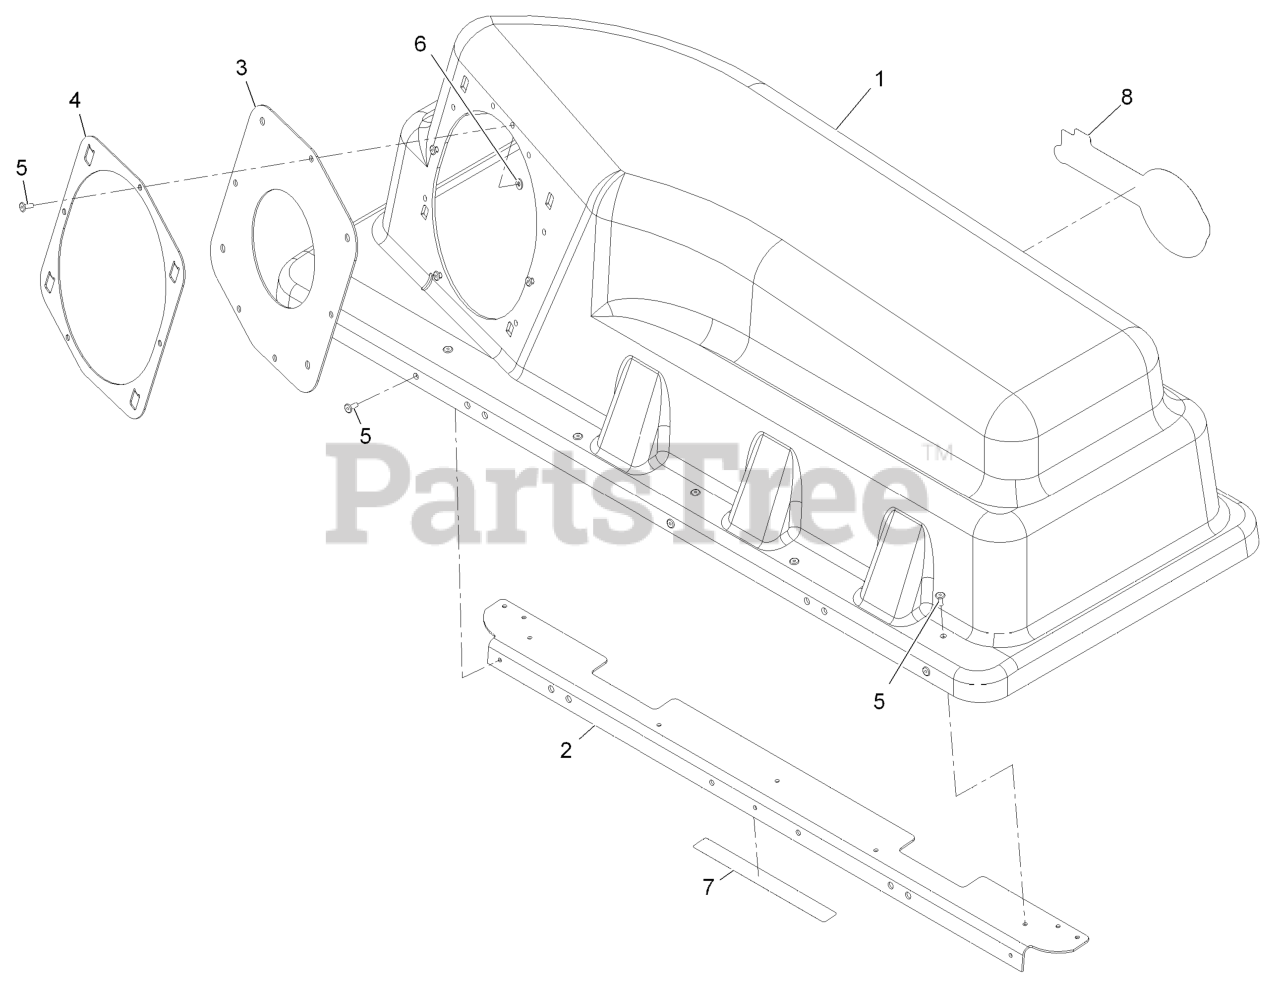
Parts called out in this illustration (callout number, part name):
1	TOP-BAGGER
2	STIFFENER-BAGGER, TOP
4	RING-RETAINER
5	RIVET-BLIND
6	WASHER-FLAT
7	DECAL-CAUTION, BAGGER
8	DECAL, EXMARK LOGO
